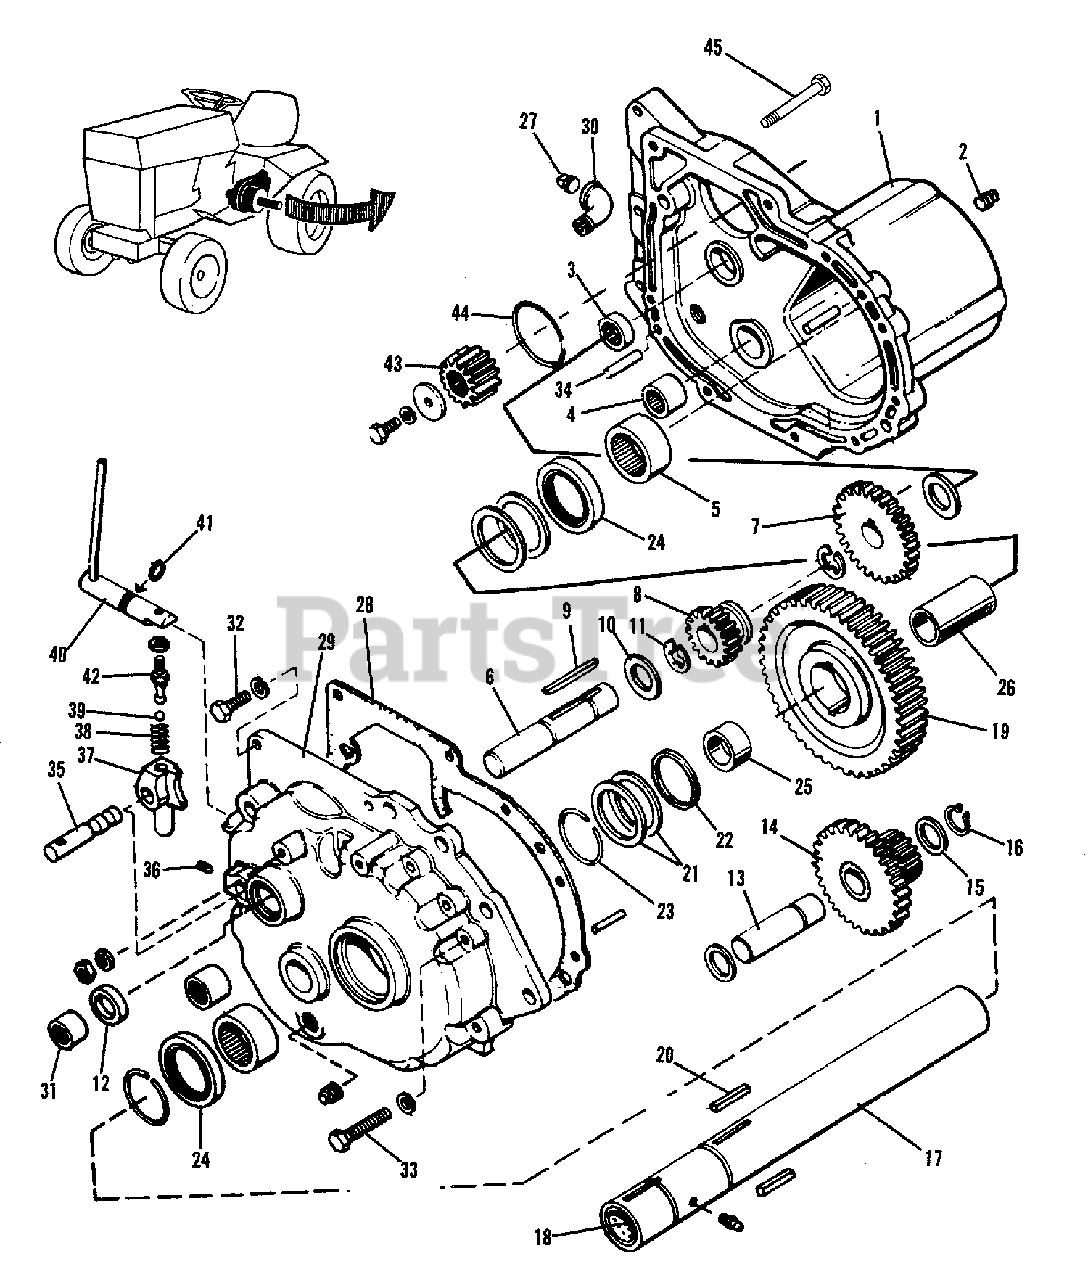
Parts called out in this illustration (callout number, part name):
1	CASE ASSEMBLY, Gear (Includes Items 3, 4 & 5)
2	PLUG, Pipe, 1/4 Standard Square Head
3	BEARING, Needle
4	BEARING, Needle
5	BEARING, Needle
6	SHAFT, Brake
7	GEAR, 1st Intermediate
8	PINION, Sliding
11	RING, Retainer
12	SEAL, Oil
13	SHAFT, Intermediate
14	PINION & GEAR ASSEMBLY
16	RING, Retainer
17	TUBE ASSEMBLY, Axle
17	FITTING, Lube, #1641 Alemite
19	GEAR, Drive
23	RING, Snap
25	SPACER, R.H., Axle
26	SPACER, L.H., Axle
27	PLUG, Pipe, 3/8, Standard, Square Head
28	GASKET, Gear Case
29	COVER ASSEMBLY, Gear Case (Includes Items 4, 5, & 31)
30	ELBOW, Street, 3/8 x 90 Degrees, Standard
31	BEARING, Needle
32	CAPSCREW, Hex. Head, 5/16NC x 1, Plated
32	LOCKWASHER, 5/16, Regular
33	CAPSCREW, Hex. Head, 5/16NC x 2, Plated
33	LOCKWASHER, 5/16, Regular
34	PIN, roll
35	SHAFT, Shifter
36	SCREW, Set, Socket Head, 5/16NC x 1/2, Plated
37	FORK, Shift
39	BALL, Shift Lock
40	SHAFT ASSEMBLY, Shift
42	STEM, Shift
42	NUT, Jam, 5/16NF
43	PINION, Motor Shaft
43	CAPSCREW, 5/16NF x 5/8
43	LOCKWASHER, 5/16
45	CAPSCREW, 7/16NC x 4, GR8
45	LOCKWASHER, 7/16
45	NUT, 7/16NC
